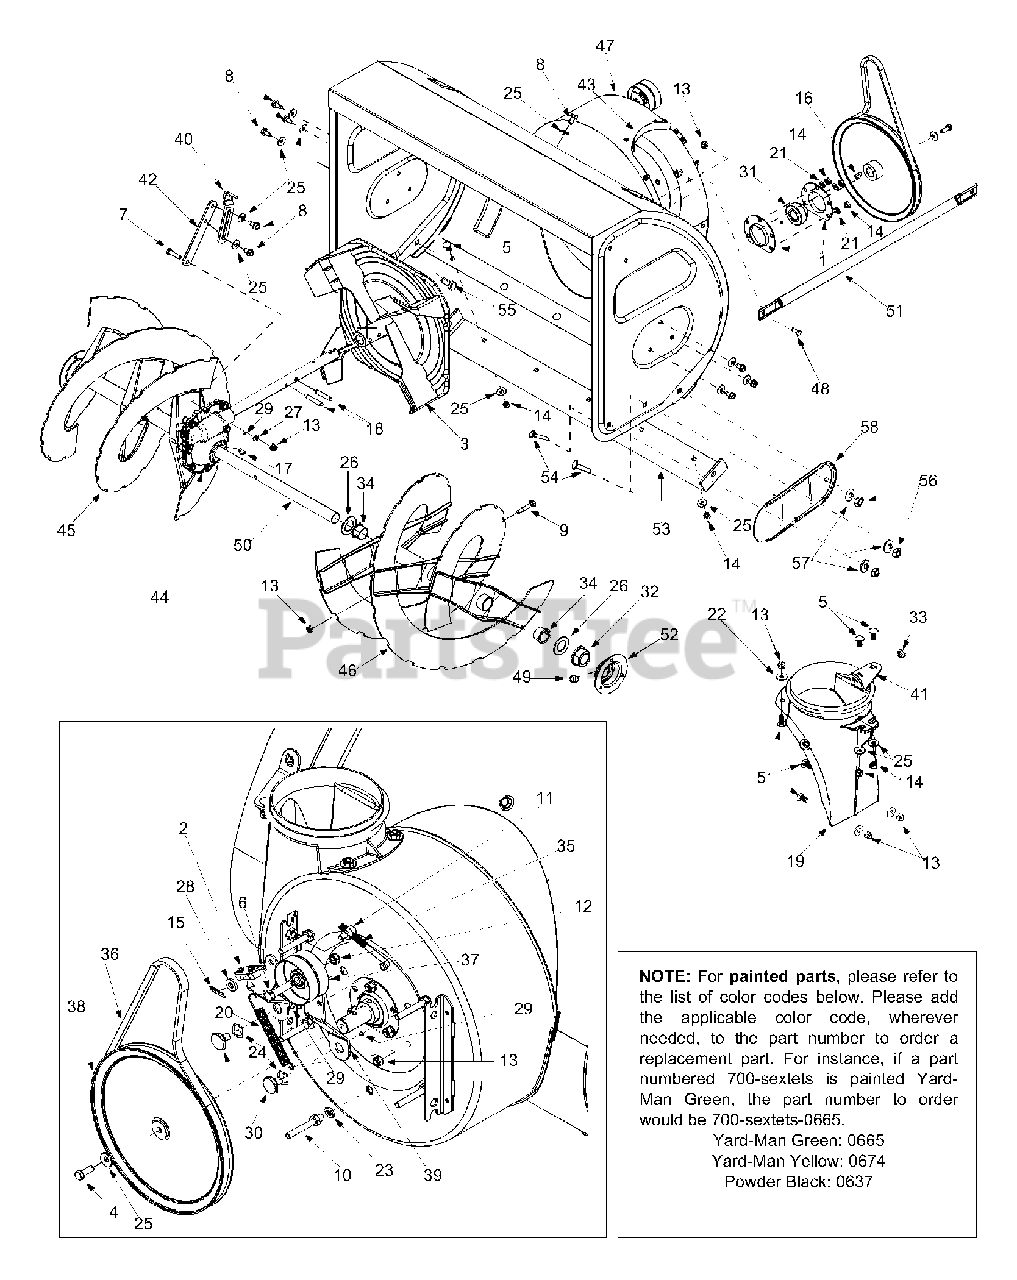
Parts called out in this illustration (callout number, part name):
1	Bearing Housing
2	Bracket Assembly: Auger Break
5	Carriage Bolt 5/16-18 x .750"
6	Hex Screw, Special 3/8-24 x 1.5"
7	Hex Screw 5/16-18 x 1.25"
8	Self-Tapp. Screw 5/16-18 x .625"
9	Shear Bolt 5/16-18 x 1.75"
11	Ferrule
12	Jam Nut 3/8-24
13	Hex Lock Nut 5/16-18
14	Hex Nut 5/16-18
15	Hairpin Clip
18	Spiral Pin
19	Chute Adapter
20	Extension Spring
21	Lock Washer
22	5/16 Washer
23	Lock Washer
24	Wave Washer
25	Beleville Washer
26	Flat Washer
27	Spring Washer
28	Flat Washer
29	Grease
30	Shoulder Screw
31	Self-Aligning Bearing
32	Flange Bearing w/ Flats
33	Plastic Bushing
34	Flange Bushing
35	Idler Rod: Auger
36	V-Belt
37	Flat Idler
38	Pulley
49	Lube Fitting
50	Spiral Axle
54	Carriage Screw
55	Carriage Bolt
56	Hex Nut 3/8-16
57	Bell Washer
